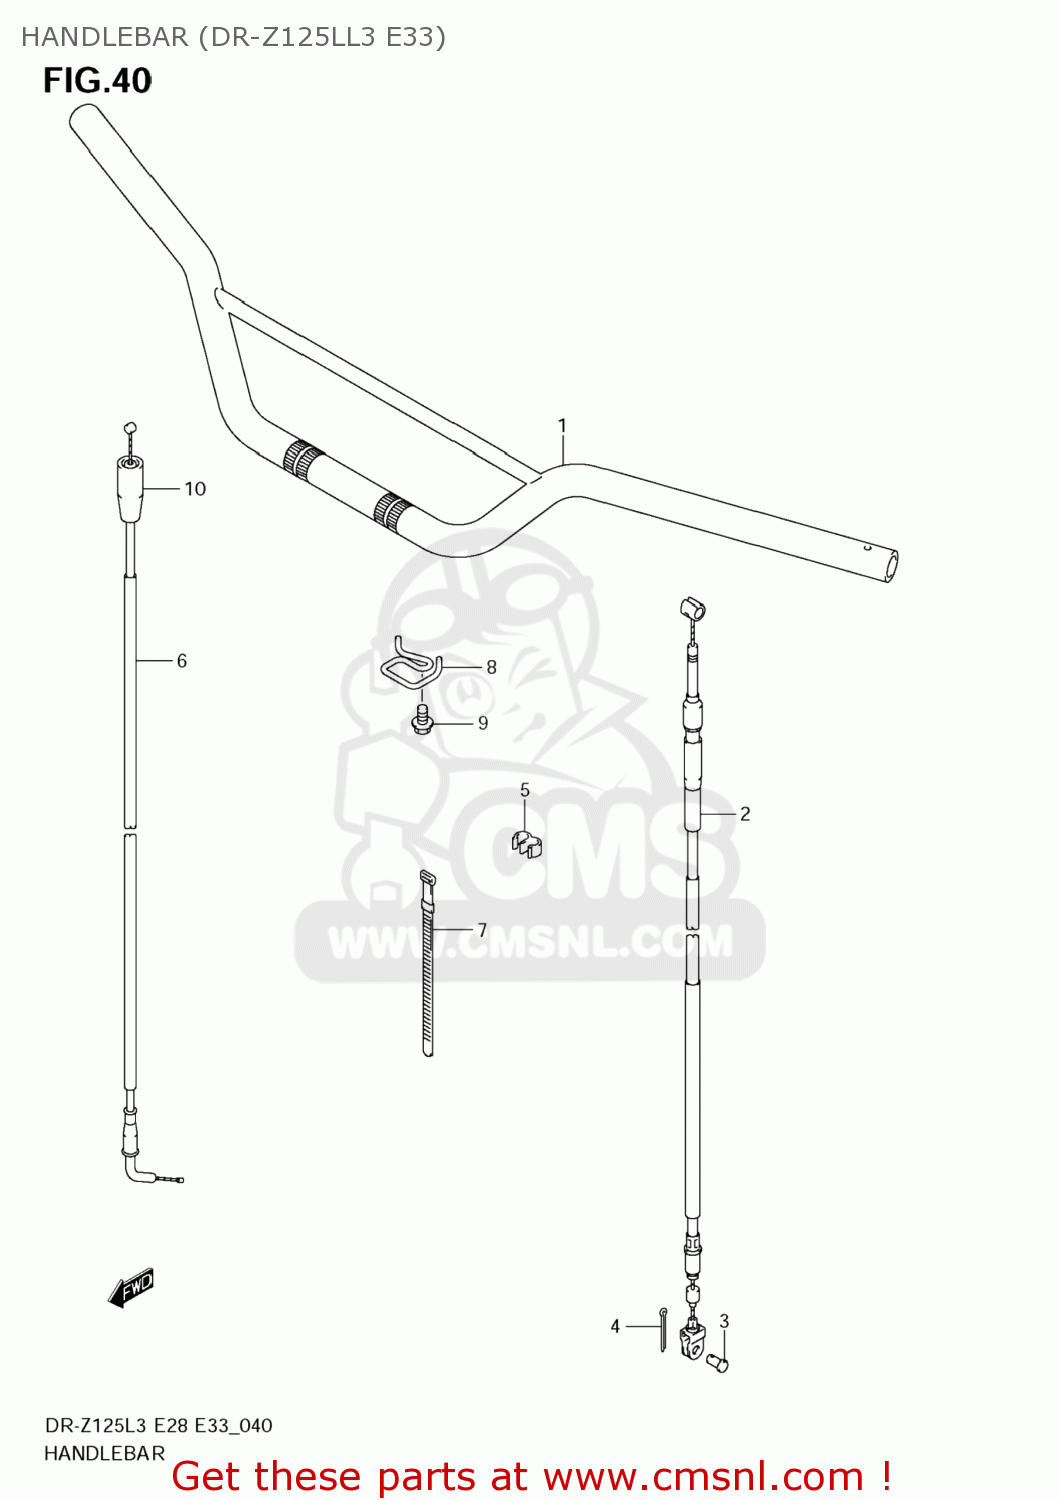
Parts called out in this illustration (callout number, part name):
1	HANDLEBAR(SILVER)
2	CABLE ASSY,CLUTCH
3	PIN(L:13)
4	PIN
5	CLAMP
6	CABLE ASSY,THROTTLE
7	CLAMP(L:90)
8	GUIDE,CABLE
9	BOLT
10	COVER,THROTTLE CASE
